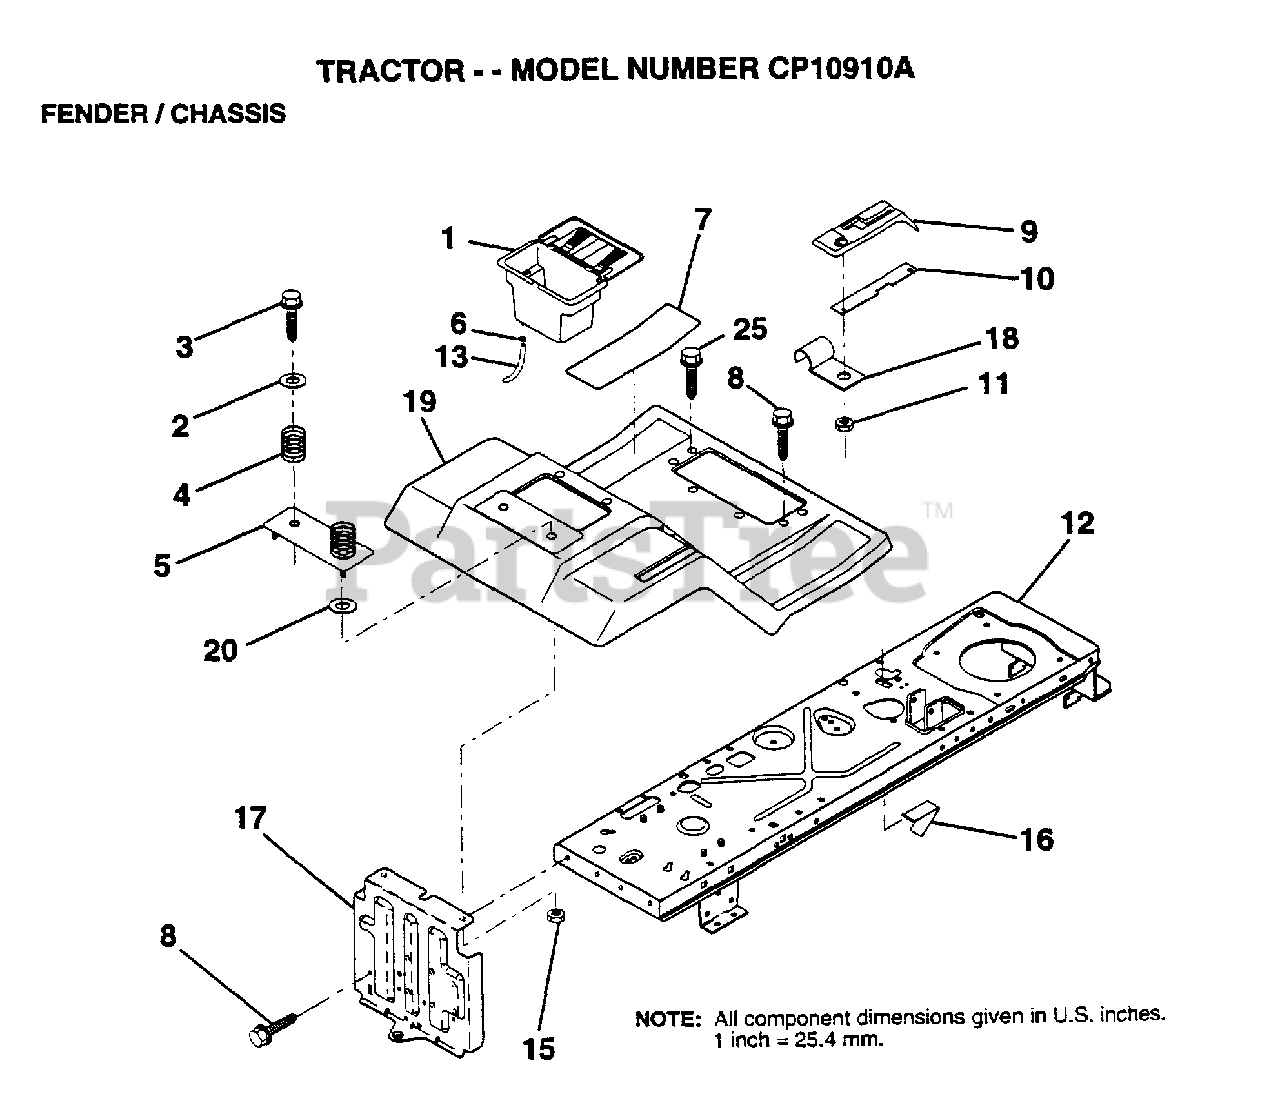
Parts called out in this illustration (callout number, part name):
2	WASHER
3	SCREW
4	SPRING COMPRESSIO
5	BTRY FENDER PLATE
6	HOSE CLAMP T
7	PAD FOOTREST
8	SCREW
9	CONSOLE SHFT 4SP
10	PLATE LOCK SHIFT
11	NUT
12	CHASSIS.WELD.ASM.
13	TUBE T
17	DRAWBAR ASM LR
18	"CLIP,INSULATOR"
19	FENDER/FOOT MS505
25	SCREW
